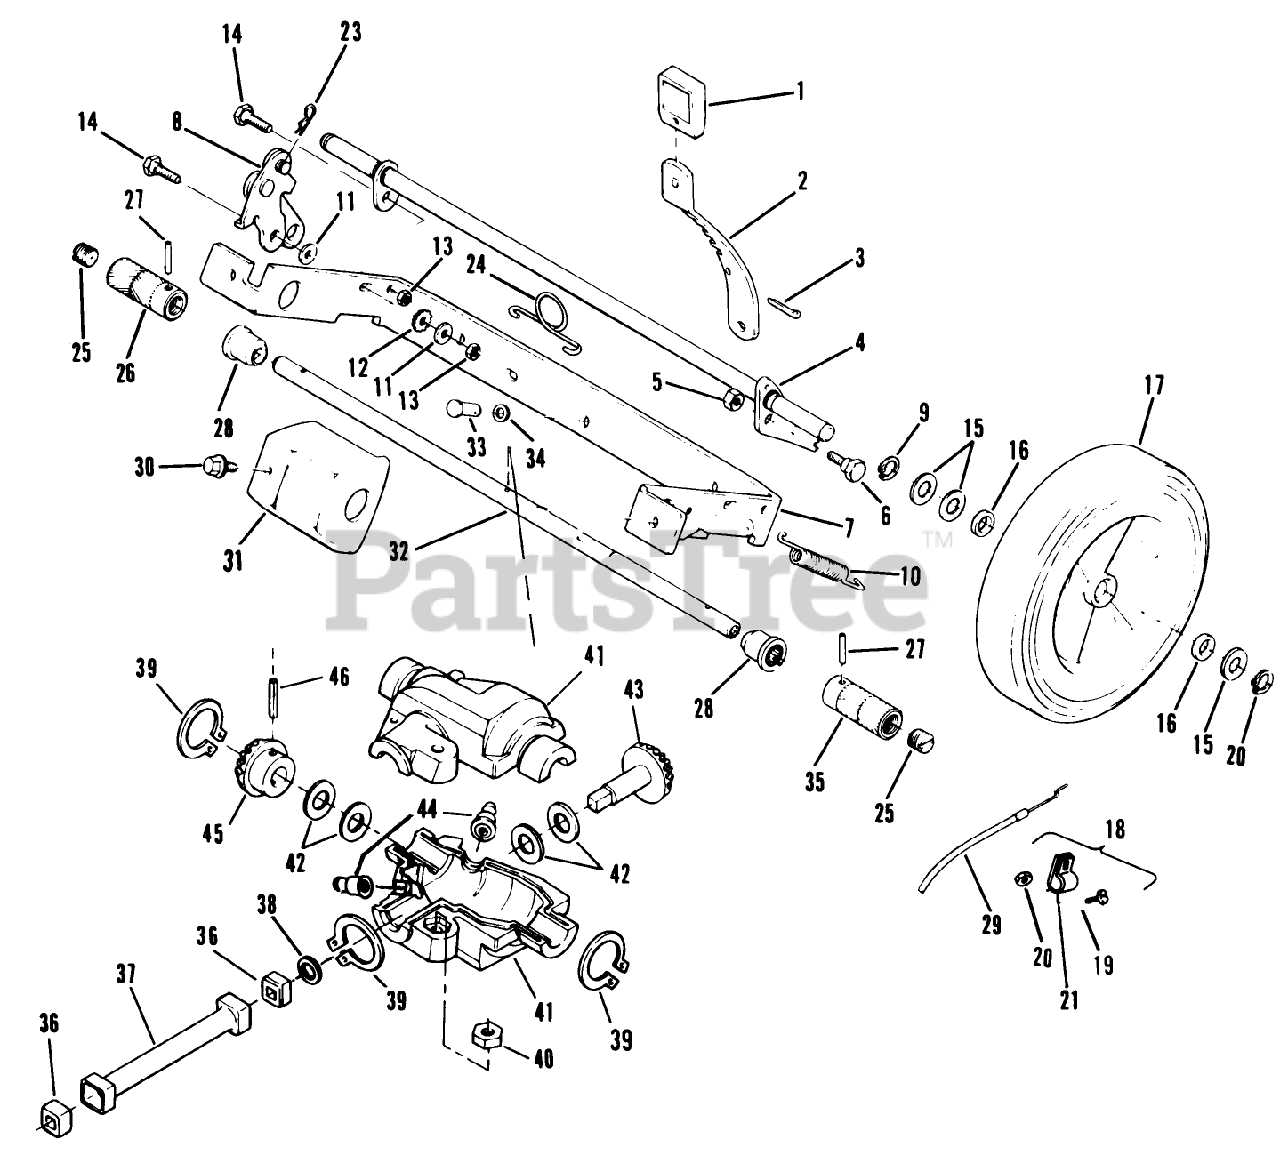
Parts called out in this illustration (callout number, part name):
1	KNOB
2	LEVER
5	LOCKNUT E
6	BOLT RB&W
7	BRK-21" AXLE
9	RET RING
10	SPRING
11	WASHER S
13	STOP NUT
14	BOLT RB&W
15	SPACER
16	WASHER
18	INTERLOCK KIT
22	RET RING
24	SPRING N.A.S
25	GREASE PLUG
26	DRIVE ROLLER
27	PIN
28	SLEEVE &BEARING AY
31	GUARD
32	PIN
33	Lever
34	WASHER SPRING LAR
35	ROLLER-LEFT
36	BUSHING
38	O-RING
40	LOCKNUT E
42	THRUST WASHER
43	GEAR BEST
44	ZERK FITTING
45	GEAR ADVANCE
46	ROLL PIN
